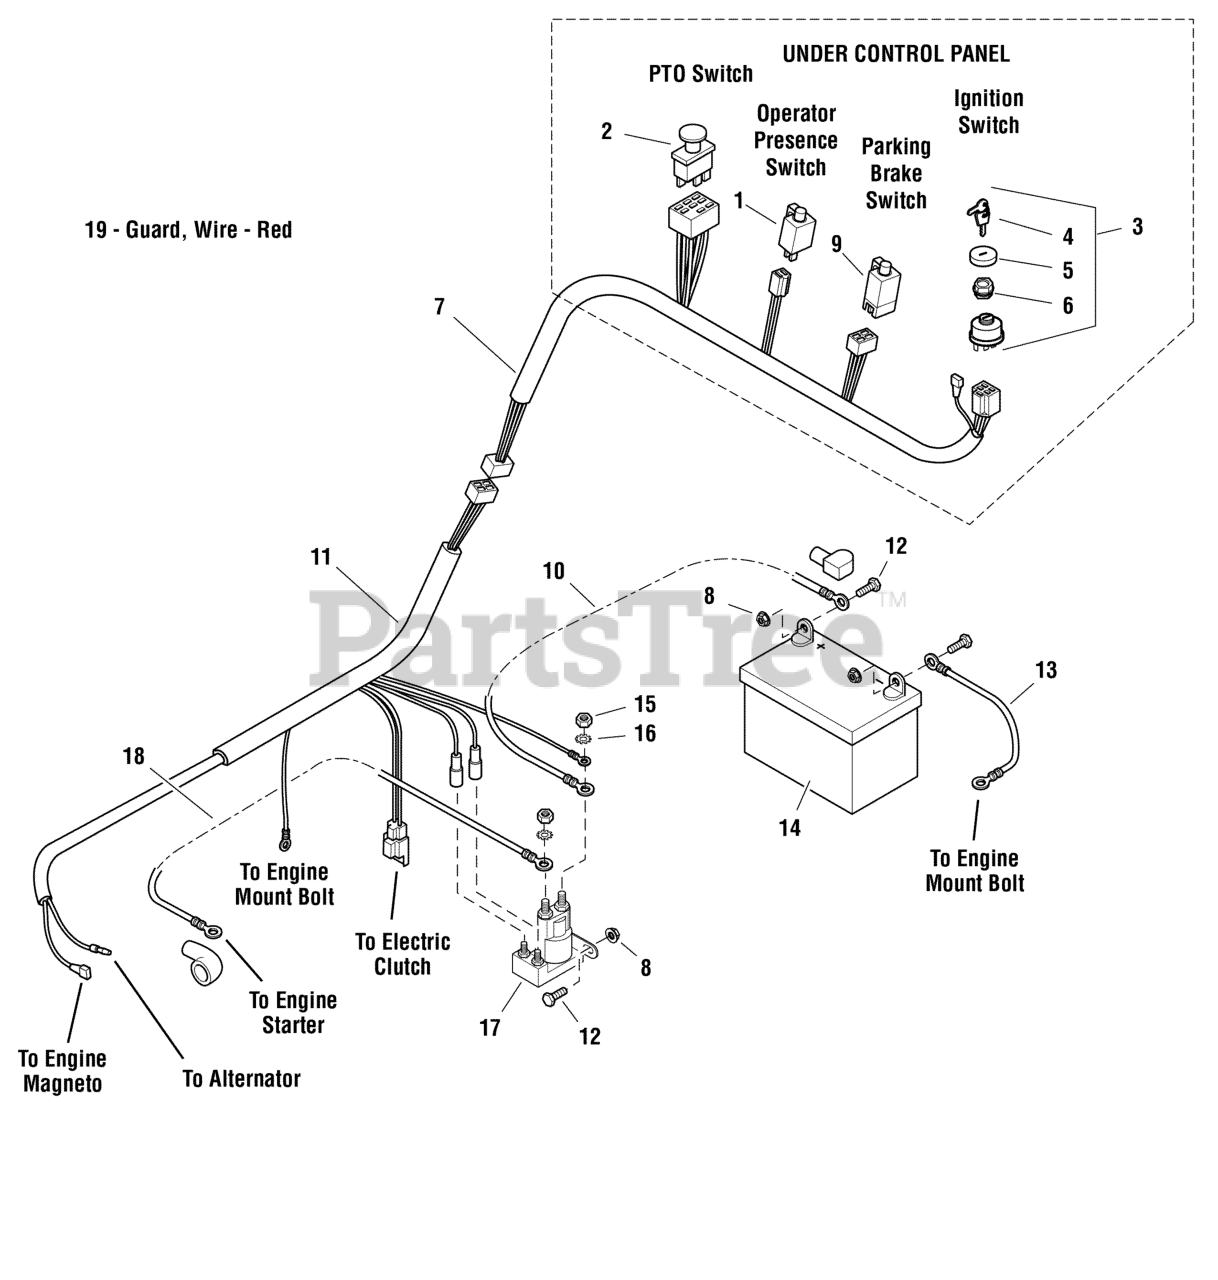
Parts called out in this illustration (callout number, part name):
1	SWITCH, PLUNGER, N.C.
2	SWITCH, BLADE ENGAGEMENT
3	SWITCH, IGNITION, 6 POST
4	KEY, IGNITION MOLDED SET
5	COVER, PLASTIC, SNAP ON
6	PLASTIC NUT
7	WIRE HARNESS, HANDLE BAR
8	NUT, 1/4-20 HEX SERR. FLANGE
9	SWITCH, PLUNGER, N.O./N.C.
10	BATTERY CABLE, POSITIVE, 22"
11	WIRE HARNESS, ENGINE DECK, KAWASAKI
12	BOLT, 1/4-20 X 3/4
13	BATTERY CABLE, NEG, 22, 1/4-5/16
13	BATTERY CABLE, NEGATIVE, 35"
14	BATTERY, WET ( BCIU1, 340 CCA)
15	NUT, HEX JAM 5/16-24
16	WASHER, LIGHT LOCK, 5/16
17	SOLENOID-4 POLE 12 VOLT DC (TROMBETTA)
18	BATTERY CABLE, POSITIVE, 30
19	GUARD, WIRE - RED
